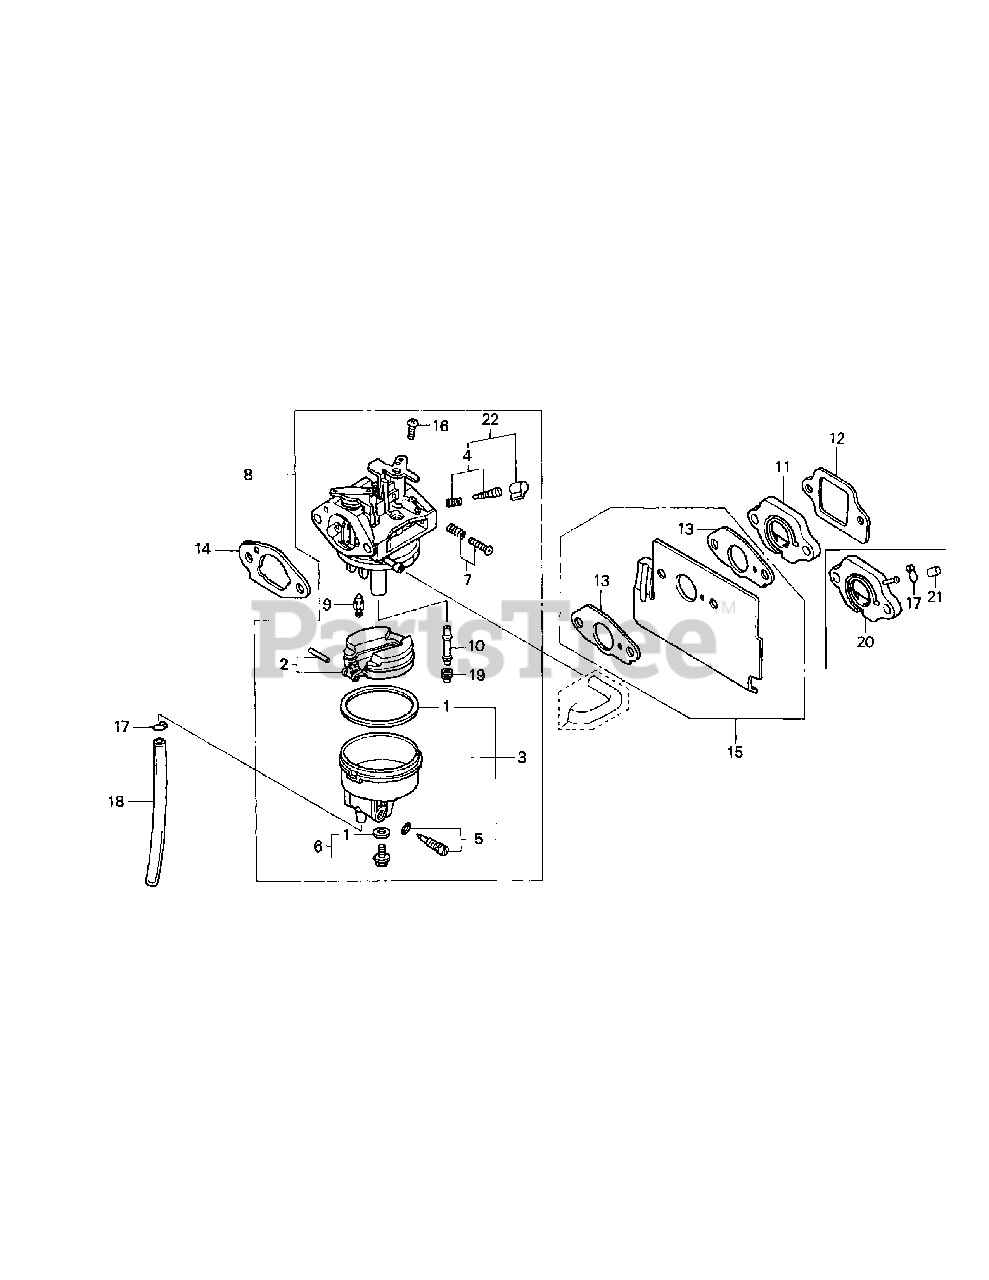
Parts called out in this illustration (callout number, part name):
1	Gasket Set
3	Float Chamber Set
5	Drain Screw Set
6	Screw Set B
8	Carburetor Assembly, BB61B C
8	Carburetor Assembly, BB61B D
9	Float Valve, Carb. No. BB61B C
9	Float Valve, Carb. No. BB61B D
10	Main Nozzle
11	Carburetor Insulator
12	Insulator Gasket
13	Carburetor Gasket
14	Carburetor Gasket, Choke Side
16	Pan Screw, 5 x 6
17	Tube Clip, B6.5
18	Vinyl Bulk Hose
19	Main Jet, #60
19	Main Jet, #62
19	Main Jet, #65
